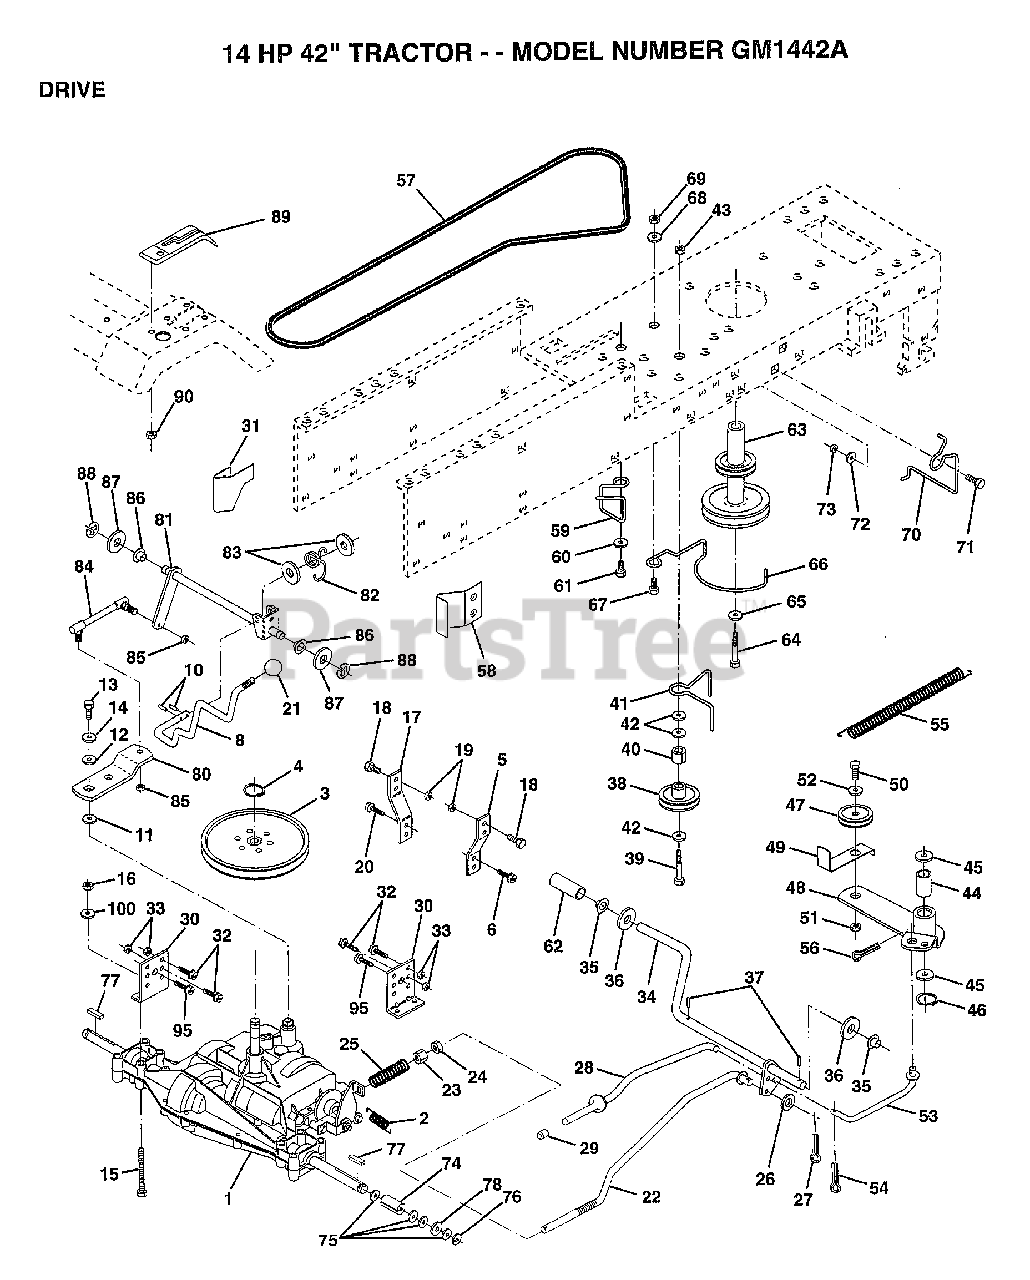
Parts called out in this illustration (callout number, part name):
3	PULLEY TRANS
5	STRAP TORQUE
6	SCREW
8	ROD SHIFT FEND LT
10	PIN COTTER 1/8
11	WASH-SHFT PLT LT
12	WASHER
14	LOCKWASHER
15	BOLT HEX
16	NUT
17	STRAP TORQUE
18	BOLT
19	NUT
20	SCREW
21	KNOB T (1/2-HOLE)
22	BRAKE ROD
23	NUT
24	NUT
25	SPRING ROD LT
26	WASHER
27	COTTER PIN
28	ROD PARK BRAKE
29	PLUNGER CAP T
30	TRANSAXLE MTG BKT
31	"KEEPER,BELT LH T"
32	BOLT
33	NUT
35	NYLON BEARING
36	WASHER LT
38	PULLEY.IDLER.FLAT
39	BOLT
40	SPACER T
41	BELT KEEPER LT
42	WASHER
43	NUT
44	"LY, BEARING"
45	WASHER LT
46	KLIP RING
48	ARM IDLER
49	RETAIN BELT
52	WASHER
53	"LINK, CLUTCH T"
54	COTTER PIN
55	"SPRING, RETURN LT"
56	COTTER PIN
58	"KEEPER,BELT RH T"
59	KEEPER BELT CNTSP
60	WASHER
61	SCREW
62	PEDAL COVER T
63	PULLEY.ENGINE
64	BOLT
65	LOCKWASHER
66	KEEPER.BELT.ENG.L
67	BOLT
68	WASHER
70	KEEPER BELT ENG
71	BOLT
72	WASHER
74	SPACER LT
75	WASHER
76	E-RING LT
77	SQUARE KEY
78	WASHER
80	SHIFT LEVER
81	SHAFT ASM SHIFT
82	"SPRING,TORSION"
83	WASHER
84	TIE ROD
85	NUT 1/4-28
86	BUSHING
87	WASHER D
88	KLIP RING
90	NUT
95	SCREW
100	WASHER M
